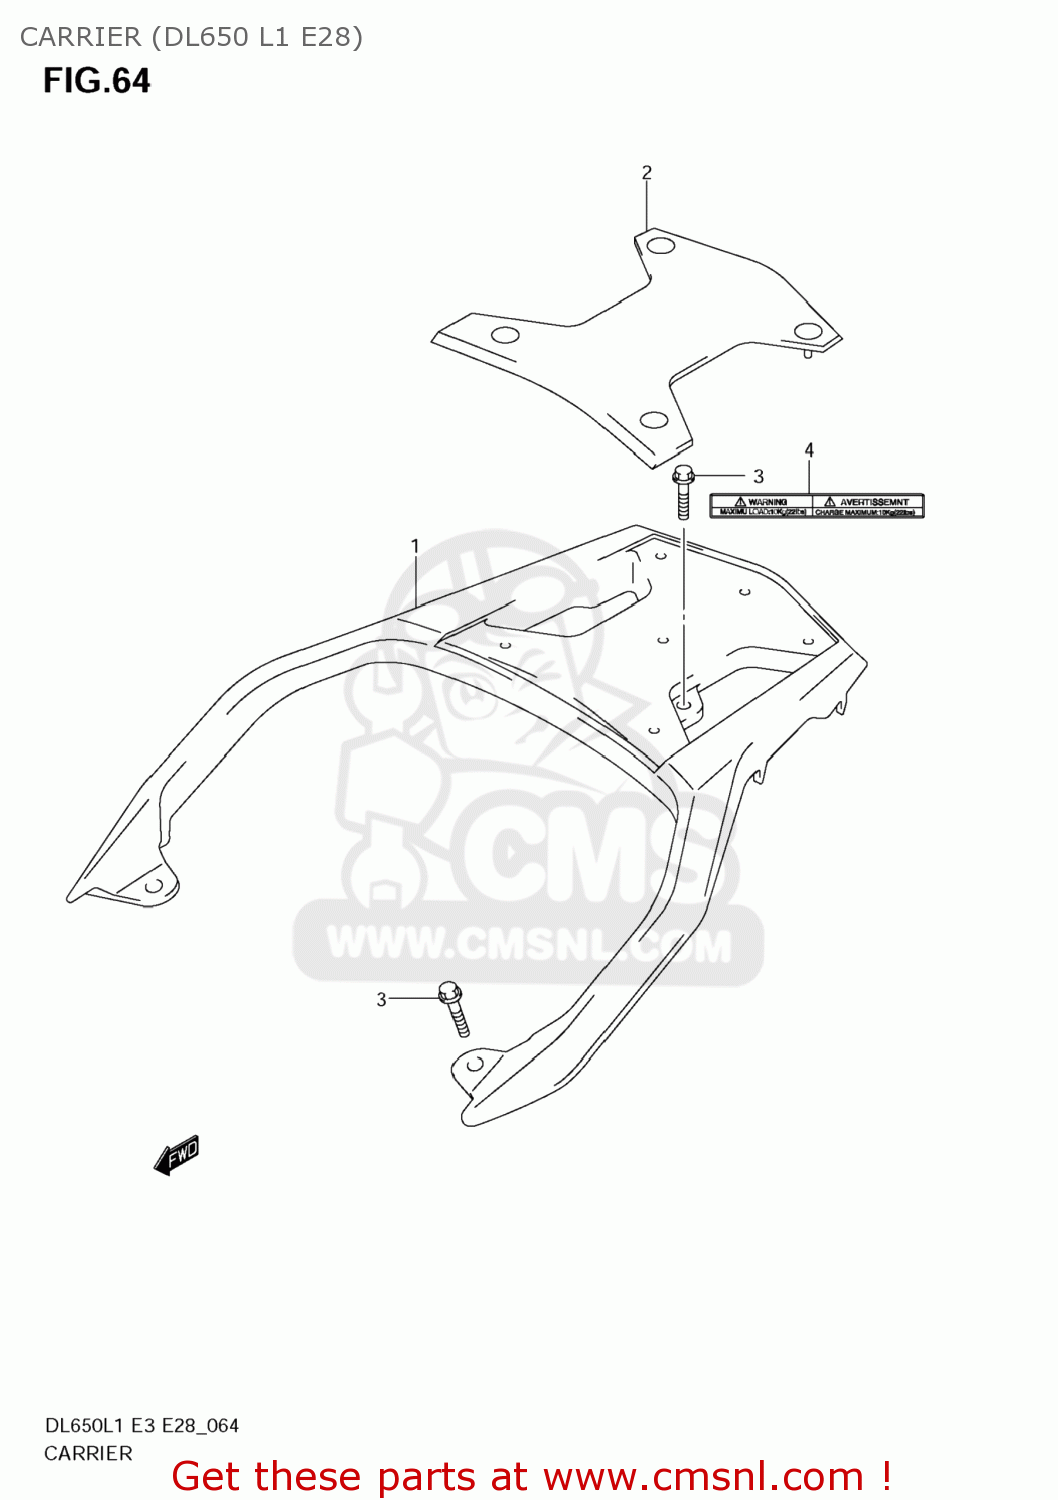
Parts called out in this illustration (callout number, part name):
1	CARRIER,SPORT
2	MAT,SPORT CARRIER
3	BOLT(8X35)
4	LABEL,CARRIER
